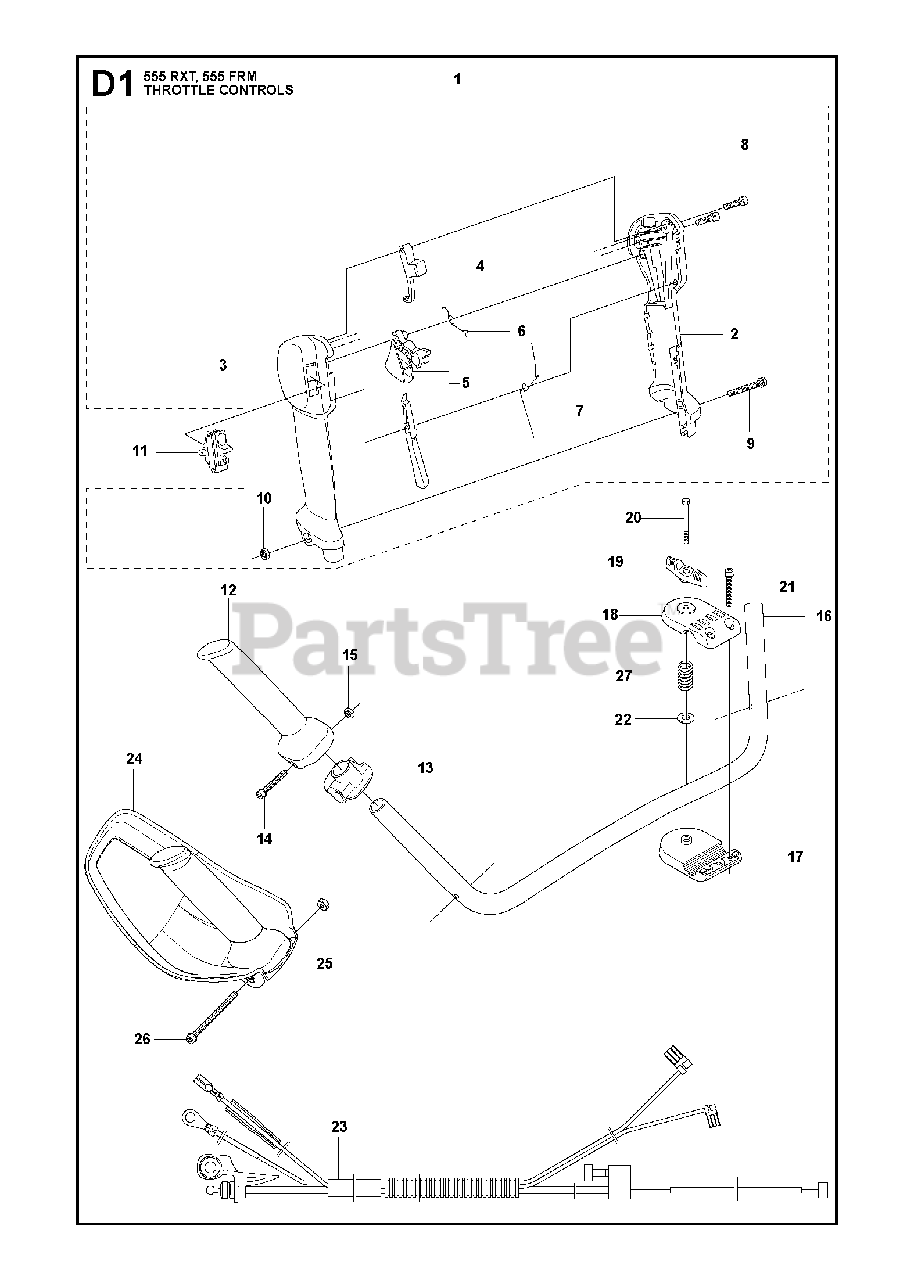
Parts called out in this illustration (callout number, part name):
1	THROTTLE HANDLE ASSY
2	HANDLE HALF RIGHT
3	HANDLE HALF LEFT
4	LOCKOUT STARTER THROTTLE
5	THROTTLE CONTROL
6	SPRING
7	SPRING
8	SCREW
9	%SCREW
10	NUT
11	STOP BUTTON
15	NUT M6M M5
16	HANDLE
17	HANDLE HOLDER LOWER
18	HANDLE HOLDER UPPER
23	WIRING
